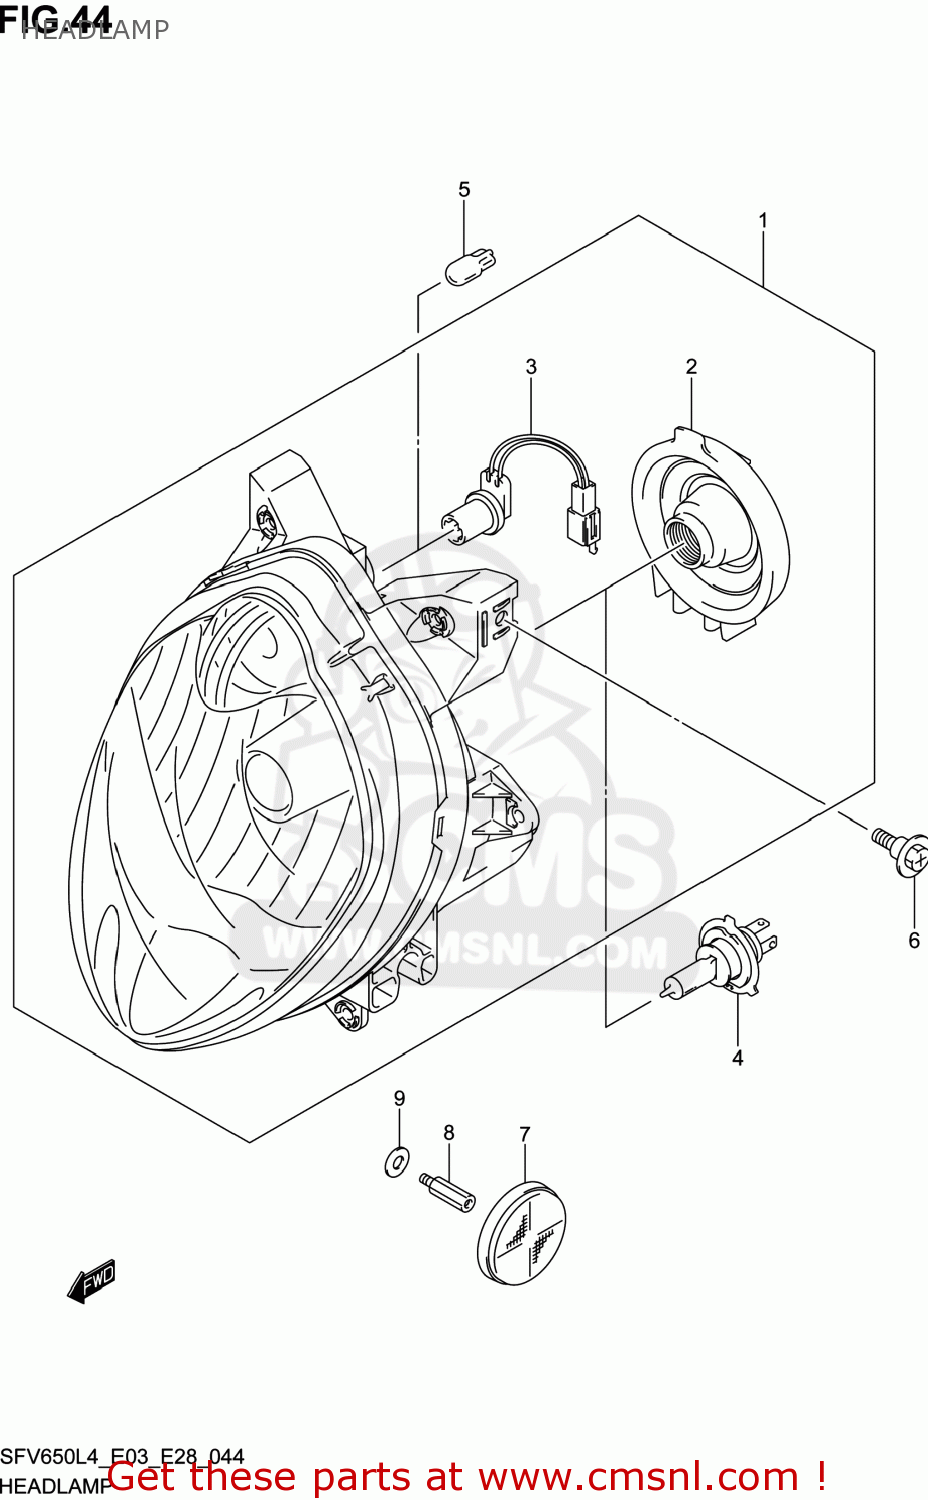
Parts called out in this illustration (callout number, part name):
1	HEADLAMP ASSY
2	COVER,SOCKET
3	CORD ASSY
4	BULB(12V60/55W,H4)
5	BULB(12V5W)
6	SCREW(6X22.5)
7	REFLEX REFLECTOR ASSY,FR SIDE
8	BOLT(5X10)
9	WASHER
